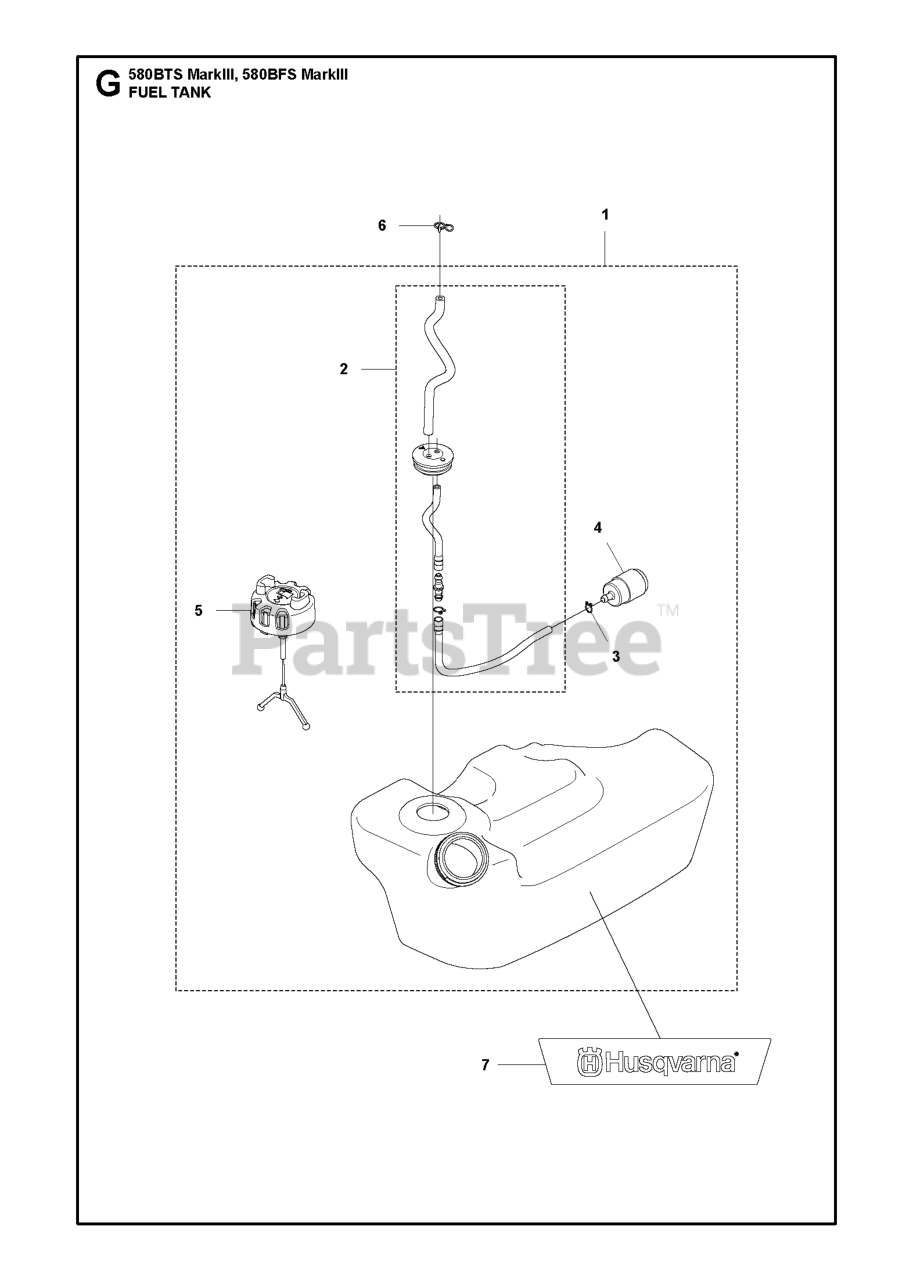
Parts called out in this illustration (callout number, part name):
1	TANK ASSY EVP
4	RP FUEL FILTER
5	FUEL CAP ASSY
